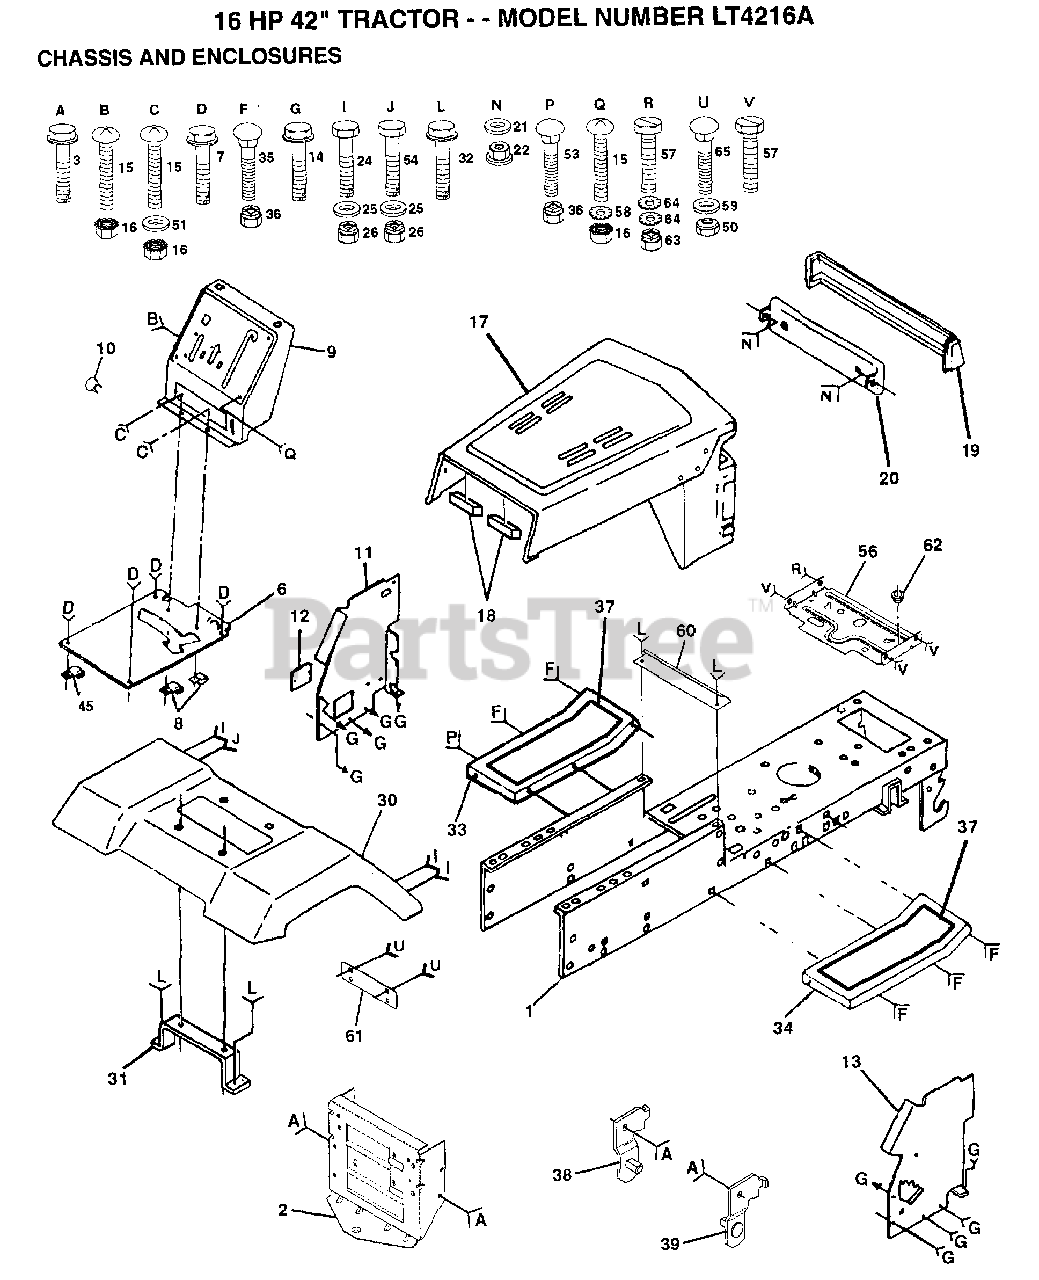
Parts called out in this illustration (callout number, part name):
3	SCREW
7	SCREW
8	CLIP T
10	PLUG BUTTON T
11	PANEL DASH LH
12	COVER ACCESS
14	SCREW LT
15	SCREW
17	HOOD/GRILLE.ASM
21	WASHER PM
22	PAL NUT LT
25	WASHER
26	NUT
31	BRACKET SUPT FEND
32	SCREW
35	BOLT
37	FOOTREST PAD
38	BRACKET ASM LH
39	BRACKET ASM RH
45	"CLIP,INSULATOR"
50	NUT
51	WASHER
57	SCREW
58	LOCKWASHER
59	WASHER
60	SPACER FENDER LT
61	PLATE EXTEN FEND
64	LOCKWASHER.5/16.E
65	BOLT D
